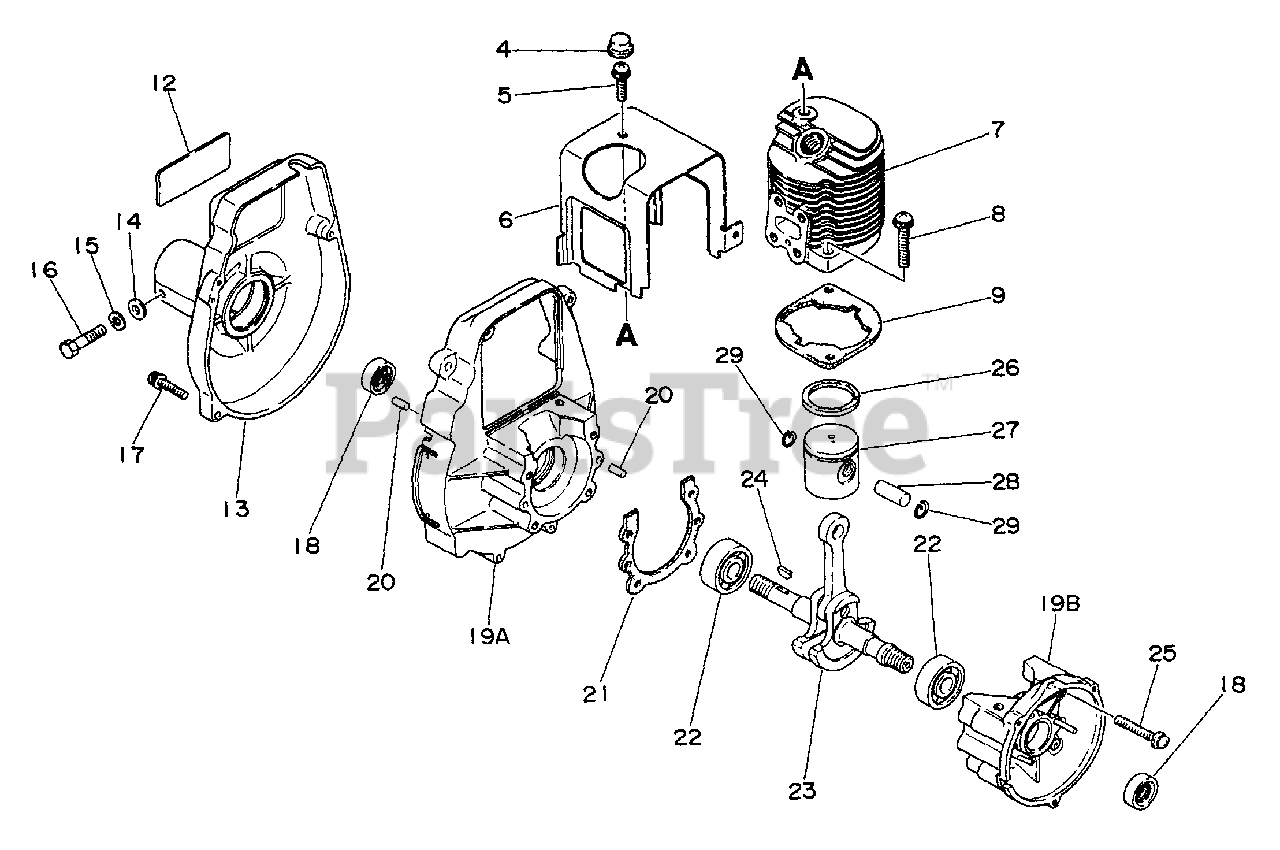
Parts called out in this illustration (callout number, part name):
5	SCREW - 5X10
6	COVER, ENGINE
7	CYLINDER
8	SCREW - 6X20
9	GASKET, CYLINDER
12	LABEL - MODEL
13	CASE, FAN
14	WASHER - 5
15	LOCKWASHER - 5
16	BOLT - 5X20
17	SCREW - 4X20
18	SEAL, OIL
19	CRANKCASE KIT
19A	CRANKCASE KIT
19B	CRANKCASE KIT
20	PIN - LOCATING
21	GASKET, CRANKCASE
22	BEARING, BALL - 6200
23	CRANKSHAFT ASSY
25	SCREW - 5X30
26	RING, PISTON
27	PISTON
28	PIN, PISTON
29	RING, RETAINING
